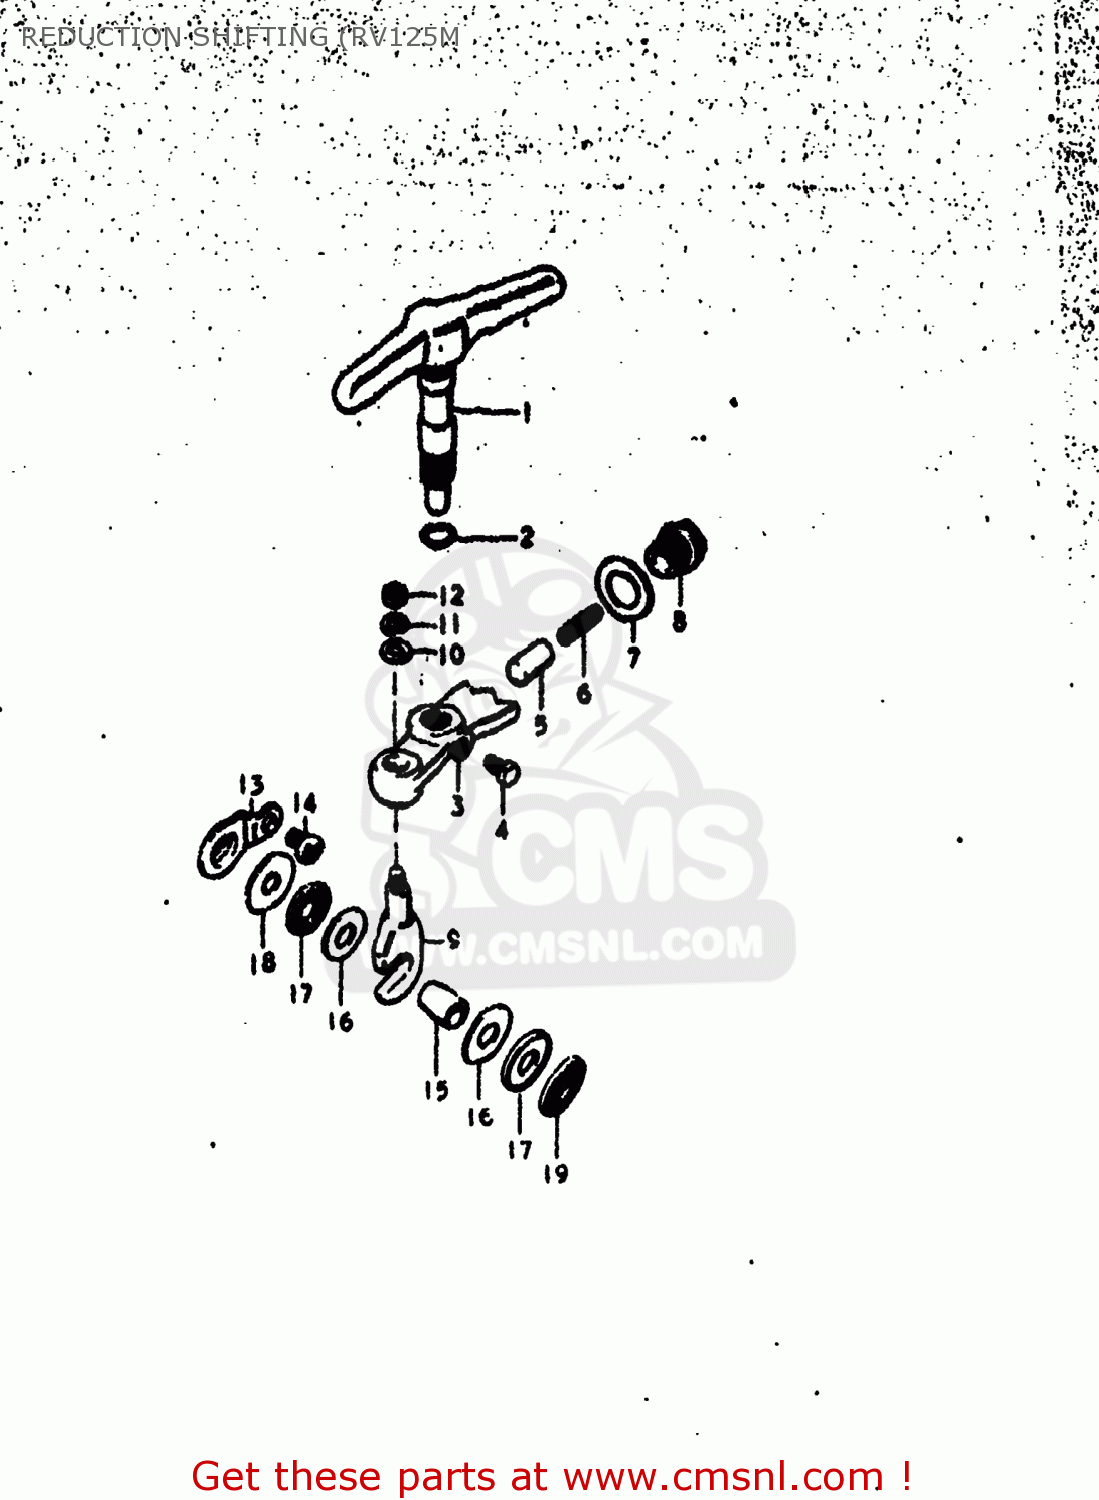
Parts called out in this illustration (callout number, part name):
1	REDUCTION SHIFTING LEVER
2	O RING(D:1.3,ID:9.6)
3	ARM,REDUCTION SHAFT
4	BOLT
5	STOPPER,GEAR SHIFTING
6	SPRING
7	WASHER (16.5X42X2.6)
8	HOLDER,SHIFTING CAM STOPPER
9	REDUCTION SHIFTING ARM PIN
10	WASHER
11	LOCK WASHER
12	NUT
13	REDUCTION ROD DUST SEAL
14	SCREW
15	SPACER(6X10X12.2)
16	WASHER(10.1X21.4X0.8)
17	BEARING(10X22X2.8)
18	WASHER
19	WASHER (6X22X2)
